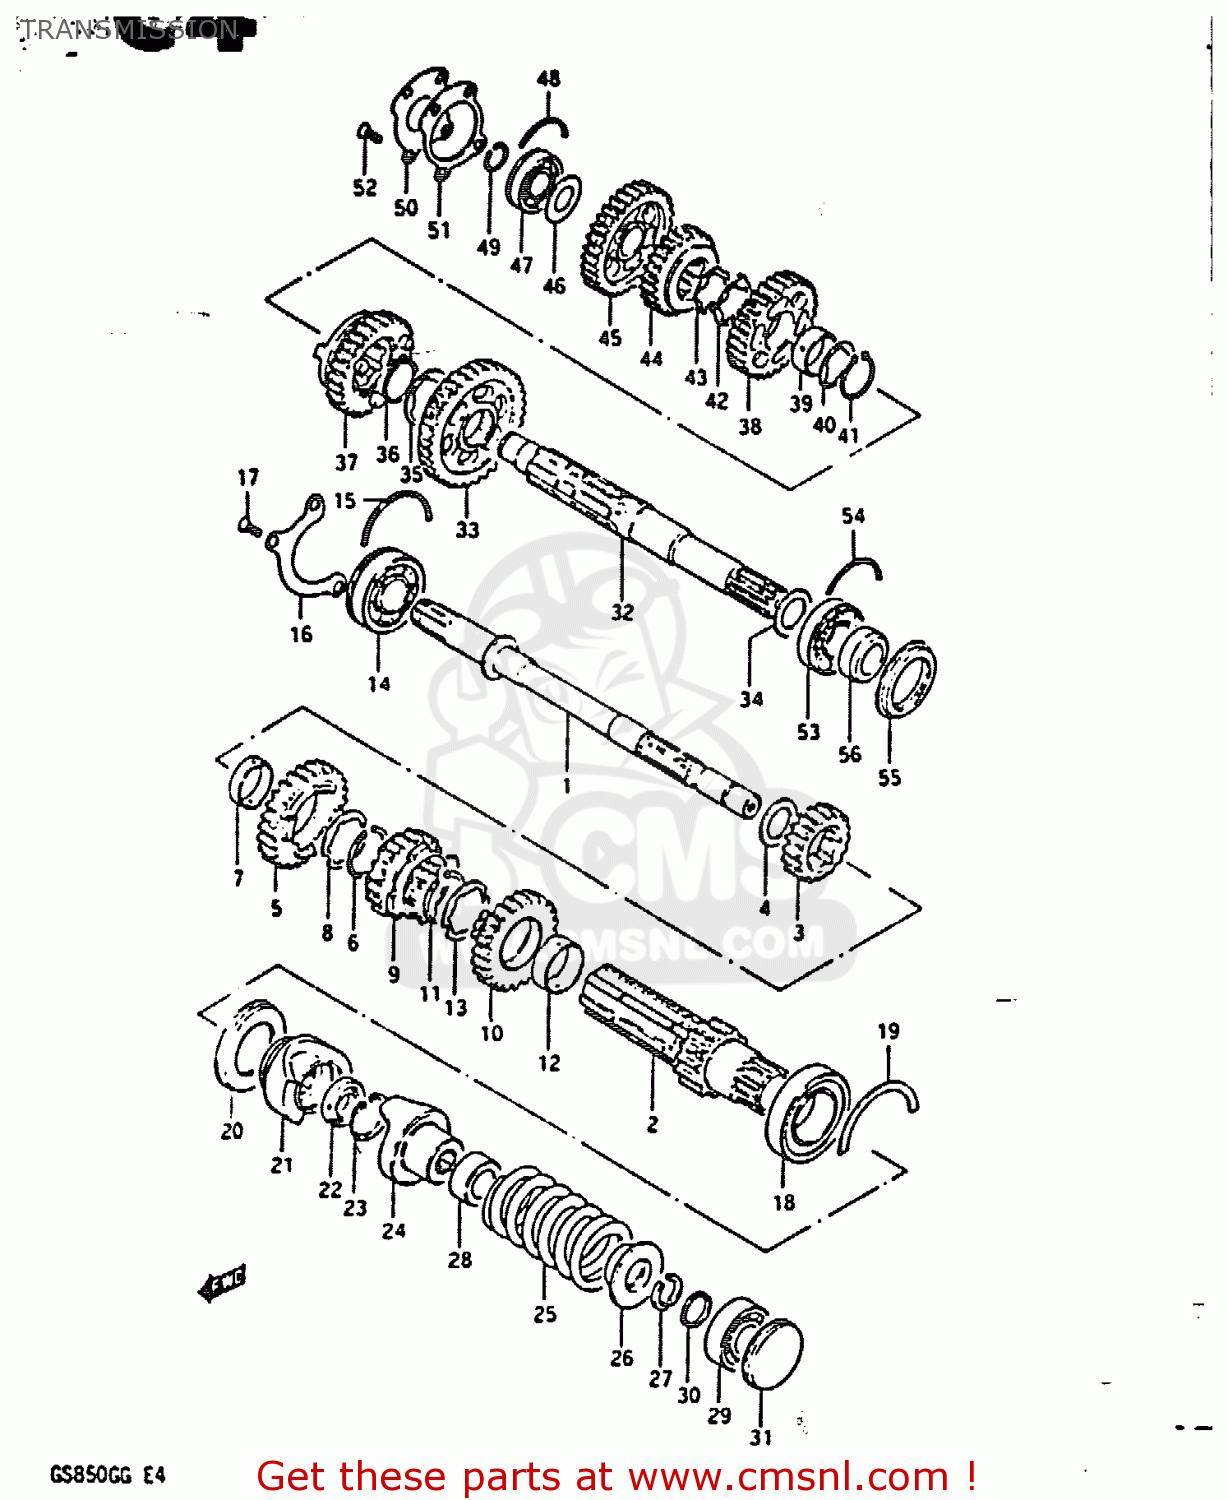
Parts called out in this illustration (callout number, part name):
1	SHAFT,INNER COUNTER
2	SHAFT,OUTER COUNTER
3	GEAR,SECOND DRIVE
4	WASHER (21X35X2)
5	GEAR,5TH DRIVE(NT:26)
6	RING,SNAP
7	SPACER,DRIVE GEAR
8	LOCK WASHER,5TH DR GEAR SPACER
9	GEAR,THIRD DRIVE
10	GEAR,FOURTH DRIVE
11	RING,SNAP
12	SPACER,DRIVE GEAR
13	LOCK WASHER,5TH DR GEAR SPACER
14	BEARING(25X62X17)
15	C-RING
16	RETAINER,CNTR SHAFT BEARING
17	SCREW
18	BALL BEARING 32X58X13
19	C-RING
20	SEAL,OIL(40X58X7)
21	DOG,OUTPUT CAM
22	SEAL,OIL(20.6X31X6)
23	CIRCLIP
24	DOG,INPUT CAM
25	SPRING
26	STOPPER,CAM DOG SLIDING
27	STOPPER,CAM DOG
28	GUIDE,CAM DOG SPRING
29	BEARING(17X40X12)
30	SPACER (17X21X3.5)
31	PLUG
32	SHAFT,DRIVE
33	GEAR,FIRST DRIVEN
34	WASHER, LH
35	WASHER,LOCK
36	CIRCLIP
37	GEAR,FOURTH DRIVEN
38	GEAR,THIRD DRIVEN
39	BUSH,3RD DRIVEN GEAR
40	WASHER,LOCK
41	CIRCLIP
42	WASHER
43	WASHER,LOCK
44	GEAR,FIFTH DRIVEN
45	GEAR,SECOND DRIVEN
46	WASHER
47	BEARING(20X47X14)
48	C RING
49	CIRCLIP
50	PLATE,DRIVESHAFT
51	GASKET,DRIVESHAFT PLATE (MCA)
52	SCREW
53	BEARING
54	C RING
55	SEAL,OIL(35X52X6)
56	SPACER,DRIVESHAFT,LEFT
